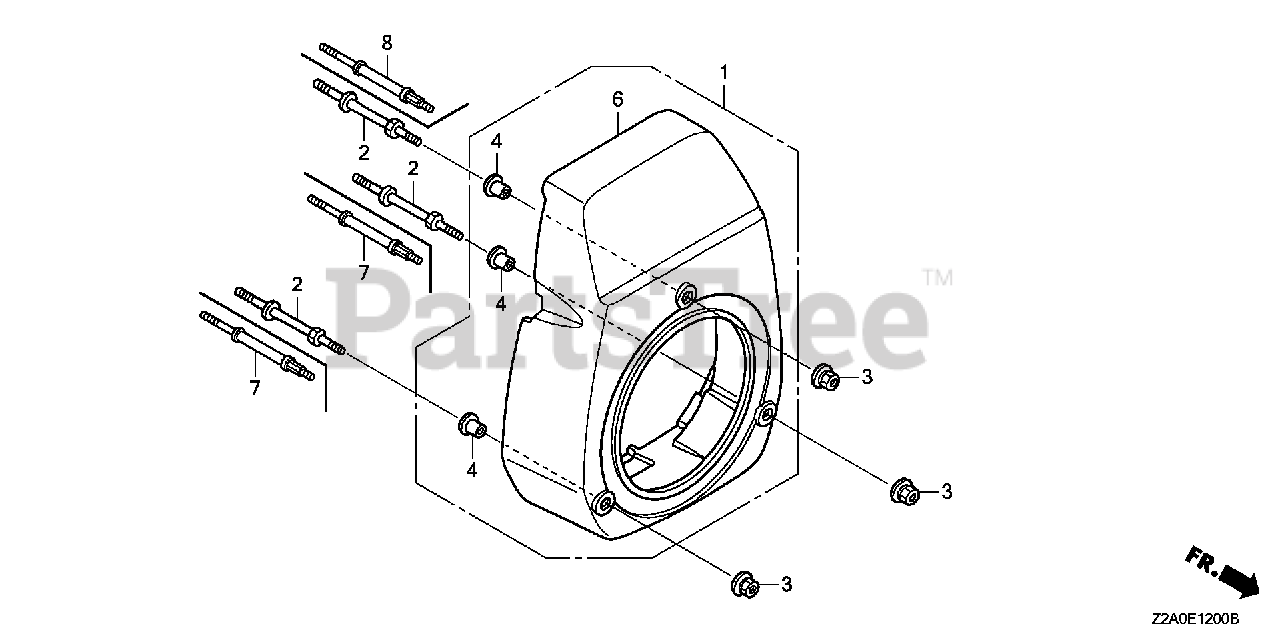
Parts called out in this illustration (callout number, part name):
3	NUT, FLANGE (6MM)
6	COVER, FAN *NH1* (BLACK)
7	BOLT, STUD (FAN COVER)
8	BOLT, STUD (FAN COVER)
